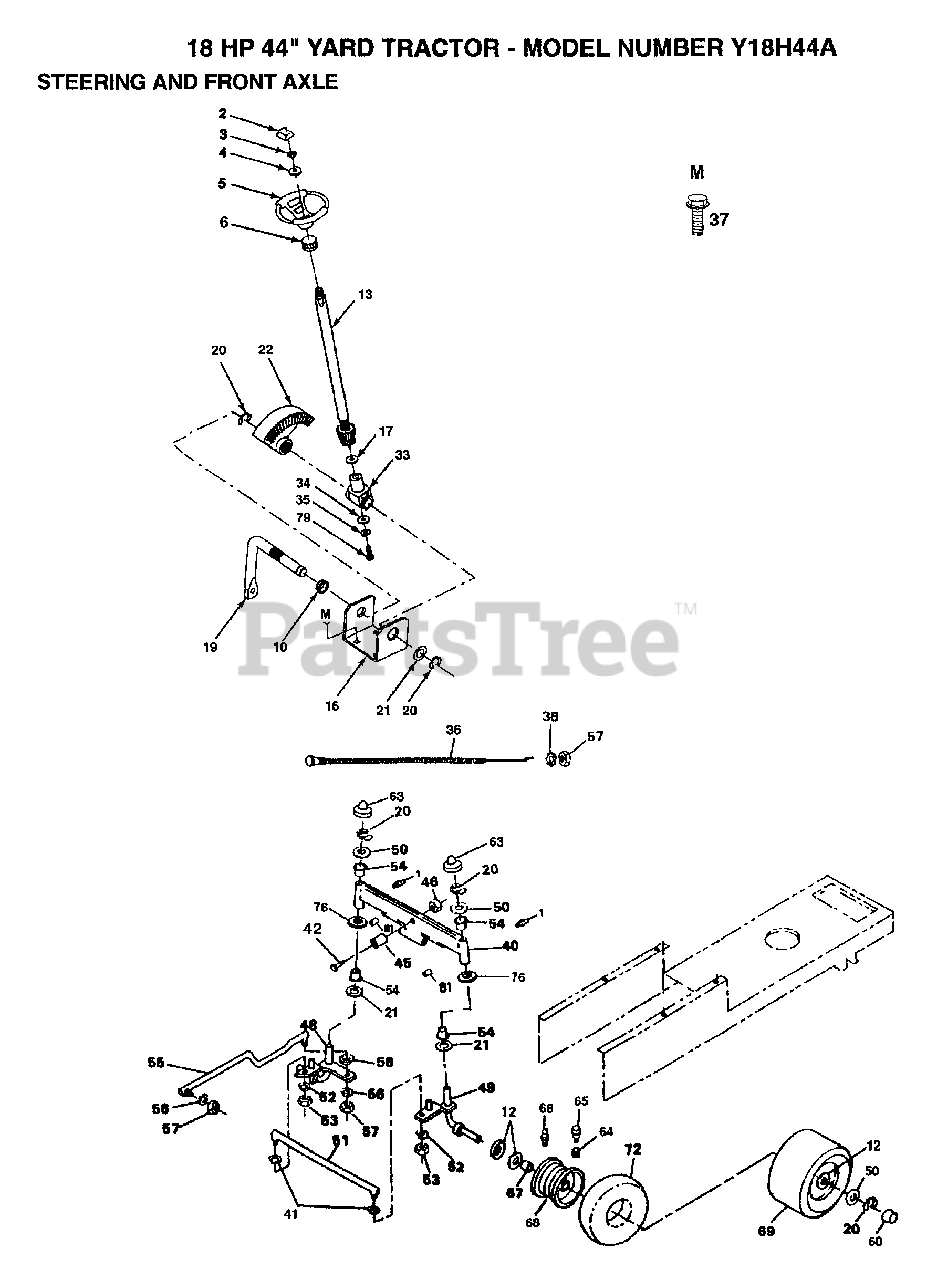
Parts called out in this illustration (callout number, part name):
1	ZERK M
2	INSERT STEERING
4	WASHER
6	ADAPTER LT
10	NYLINER T
12	WASHER
16	"BRKT,STEERING"
17	THRUST WASHER
20	RING
21	WASHER .T
24	DASH-LOWER YT
30	SPACER
33	SUPPORT.SHAFT
35	LOCKWASHER
36	CHOKE CONTROL
37	SCREW
38	LOCKWASHER
40	FRONT AXLE
41	WASHER M
42	BOLT HEX 5/8-11
45	BEARING
49	SPINDLE ASM RH
50	WASHER
51	TIE ROD
52	LOCKWASHER
53	NUT.LOCK.5/16-24
54	WASHER .T
56	LOCKWASHER
60	HUB CAP
63	CAP
64	VALVE CAP
65	VALVE STEM LT
66	FITTING LT
67	"FLANGE, BEARING"
72	TUBE.5.3/4.5/6
76	WASHER
79	"SCREW,SPECIAL"
81	AXLE PIN
